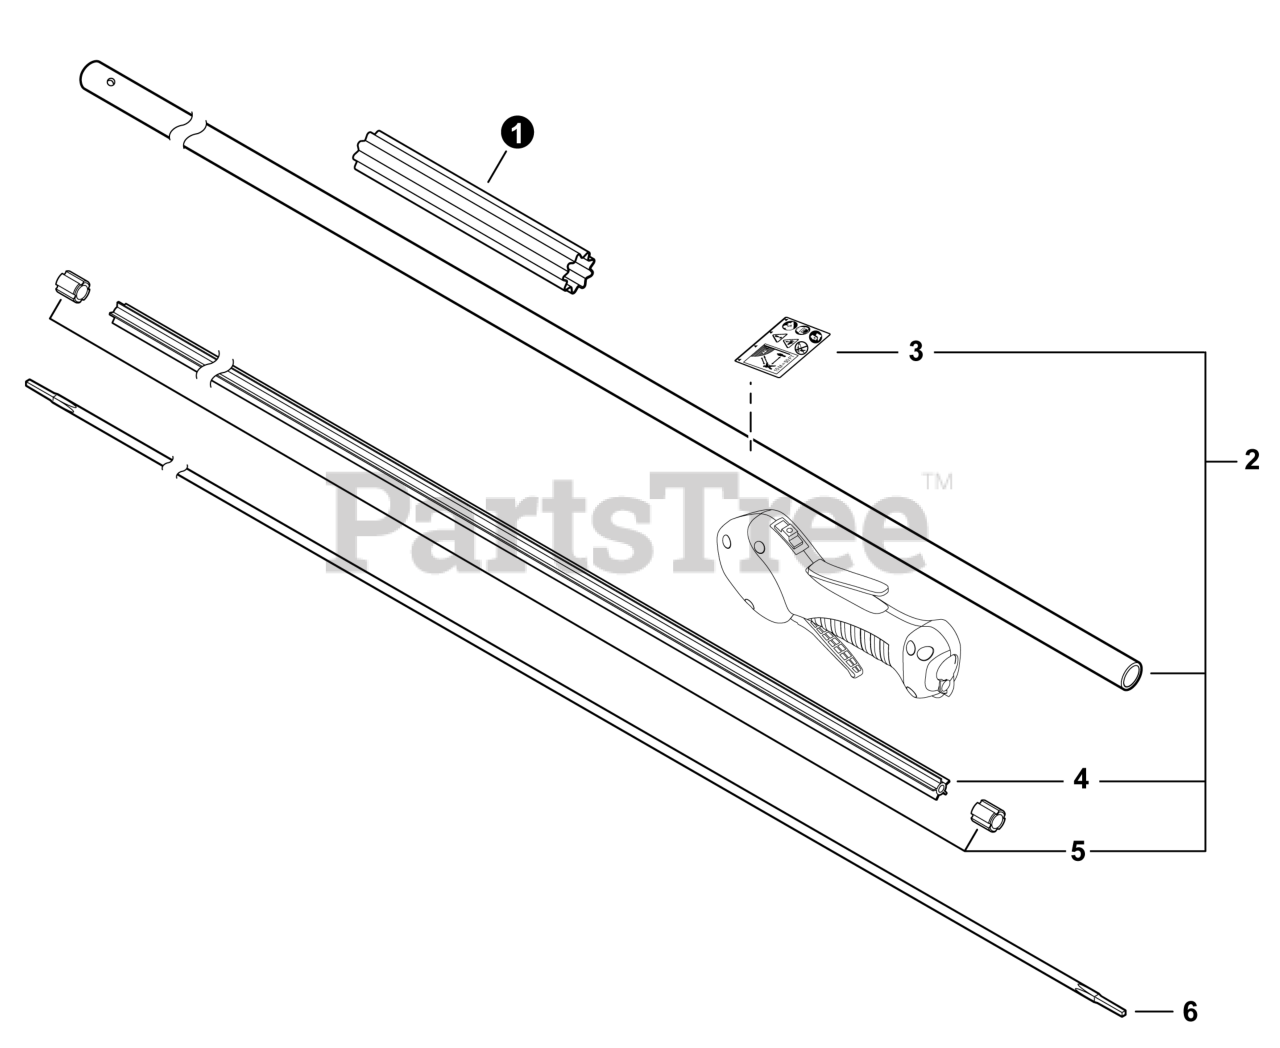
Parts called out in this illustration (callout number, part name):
1	STOPPER, HANDLE
2	MAIN PIPE ASSY
3	LABEL - CAUTION ISO
4	LINER - FLEXIBLE
6	DRIVESHAFT - FLEXIBLE
